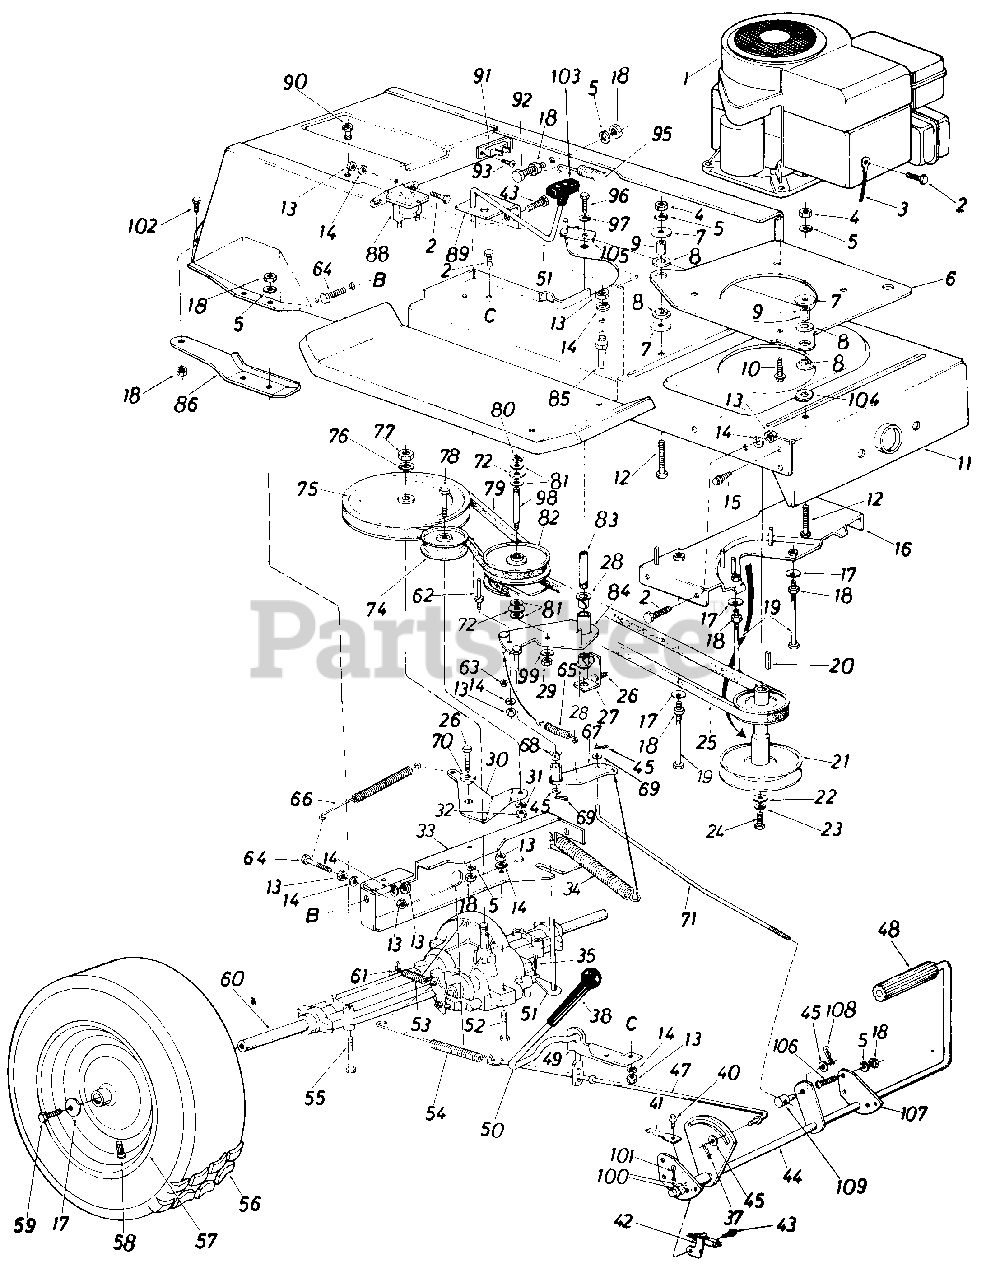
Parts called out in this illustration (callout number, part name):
2	Hex Bolt 1/4-20 x .62" Lg.
3	Electric Ground Wire
4	Hex Nut 5/16-24 Thd.
5	L-Wash. 5/16" I.D.
6	Engine Mounting Plate
7	Fl-Wash. .320" I.D. x 1.25"
8	Engine Mounting Grommet
9	Spacer
10	Hex Bolt 3/8-16 x 1.25" Lg.
11	Lower Frame Ass'y.
12	Hex Bolt 5/16-24 x 1.25"
13	Hex Nut 1/4-20 Thd.
14	L-Wash. 1/4" I.D.
15	Hex Wash. Hd. AB-Tap Scr. 5/16" x .75" Lg.
16	Belt Guard Brk't. Ass'y.
17	Bell-Wash. .345" I.D. x .88"
18	Hex Nut 5/16-18 Thd.
19	Hex Bolt 5/16-18 x 4.00"
20	Sq. Key 1/4" x 1/4" x 2.00"
21	Engine Pulley
22	Fl-Wash. 7/16" I.D. x 1.25"
23	L-Wash. 7/16" I.D.
24	Hex Bolt 7/16-20 x 1.50" Lg.
25	Variable-Speed Belt .715 x 53" Lg.
26	Hex Bolt 5/16-18 x .75" Lg.
27	Bearing Shaft Bracket
28	Flanged Nyliner Brg. 5/8" I.D. x .88" Lg.
29	Hex Nut 3/8-24 Thd.
30	Idler Bracket
31	L-Wash. 3/8" I.G.
32	Hex Nut 3/8-24 Thd.
33	Transaxle Support Brk't.
34	Ext. Spring .99" O.D. x 6.7
35	Cotter Pin 1/8" Dia. x 1.0"
37	Cotter Pin 3/32" Dia. x 1.0"
38	Grip Black
40	Hex Wash. Hd. Self-Tap Scr. 1/4-20 x .50" Lg.
41	Switch Actuator
42	Safety Switch
43	Hex Wash. Hd. AB-Tap Scr. 1/4 x .62" Lg.
44	Clutch & Brake Pedal Ass'y.
45	Fl-Wash.
47	Brake Rod
48	Foot Pad
49	Brake Lever Bracket
50	Hill Holder Brake Handle
51	Shift Lever Ass'y.
52	Hex Bolt 1/4-28 x 1.75" Lg.
53	Ext. Spring .38" O.D. x 2.5"
54	Ext. Spring .59" O.D. x 7.08"
55	Hex Bolt 5/16-18 x 2.50"
58	Air Valve
59	Hex Bolt 5/16-24 x .75" Lg.
60	Transaxle Complete
61	Brake Return Spring Anchor
62	Belt Guard Pin 1/4-20 Thd.
63	Cap Speed Nut 1/4" Dia.
65	Ext. Spring .50" Dia.
66	Ext. Spring .56" O.D. x 5.96"
67	Variabl e Speed Torque Brk't. Ass'y.
68	Flanged Bearing
69	Cotter Pin 3/32" Dia.
70	Shoulder Spacer .500" Dia. x .27" Lg.
71	Speed Control Link
72	Truss Bearing .56 Dia. x 1 .25 "
74	Fl-ldler Pulley 3.25" x 1.0"
75	1/2" "V"-Pulley 8" O.D. x .5" I.D.
76	L-Wash. 1/2" I.D.
77	Hex Jam Nut 1/2-20 Thd.
78	Hex Bolt 3/8-24 x 1.50" Lg.
79	Variable Speed Belt .715 x 44" Lg.
80	Snap Ring .56" Dia.
81	Fl-Wash.
82	Variable Speed Pulley Ass'y. 5" O.D.
83	Bearing Shaft
84	Variable Speed Brk't. Ass'y.
85	Belt Guard Pin 1/4" Dia. x 1.68" Lg.
86	Transaxle Support Brk't. R.H.
88	Solenoid
89	Shift Lever Bracket
90	Nyliner Brg. .375" Dia.
91	Ci rcu it Breaker
92	Hex Bolt 5/16-18 x 1.25" Lg.
93	Truss Hd. Phil. Scr. #10 x 1/2" Lg
95	Ext. Spring .99" O.D. x 11.0"
96	Hex Bolt 3/8-24 x .75" Lg.
97	Bell-Wash. .38" I.D. x .88"
98	Shaft .56" Dia. x 3.875" Lg.
99	Bell-Wash. .39" I.D. x 1.12"
100	Fl-Wash.
101	Cotter Pin
102	Hex Wash. Hd. Scr. 5/16-18 x .62" Lg.
103	"T" Shift Knob
104	Fl-Wash. .32" I.D. x 1.25"
105	Belt Guard
106	Truss Mach. Scr. 5/16-18 x .75" Lg.
107	Pedal Brk't.
108	Hairpin Cotter 118" Dia.
109	Ferrule
